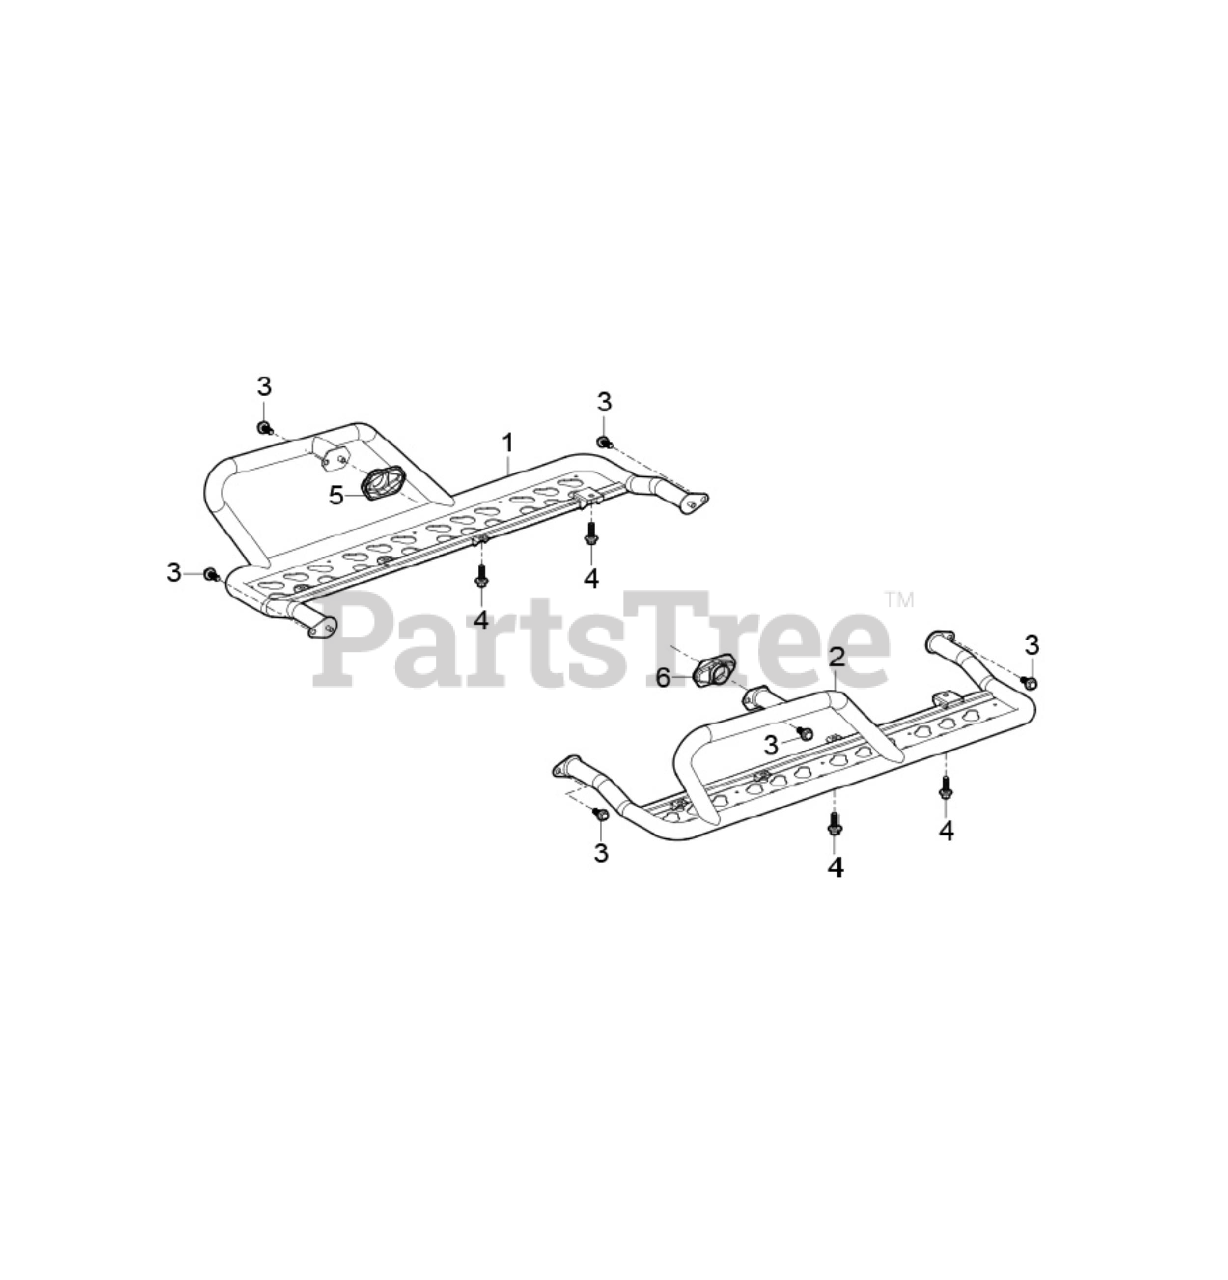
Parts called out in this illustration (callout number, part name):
1	FOOTREST PROTECTOR FRAME - LEFT
2	FOOTREST PROTECTOR FRAME - RIGHT
3	FLANGE BOLT M10X1.25X16
4	HEXAGON FLANGE BOLT M8X20
5	PROTECTION COVER - LEFT
6	PROTECTION COVER - RIGHT
